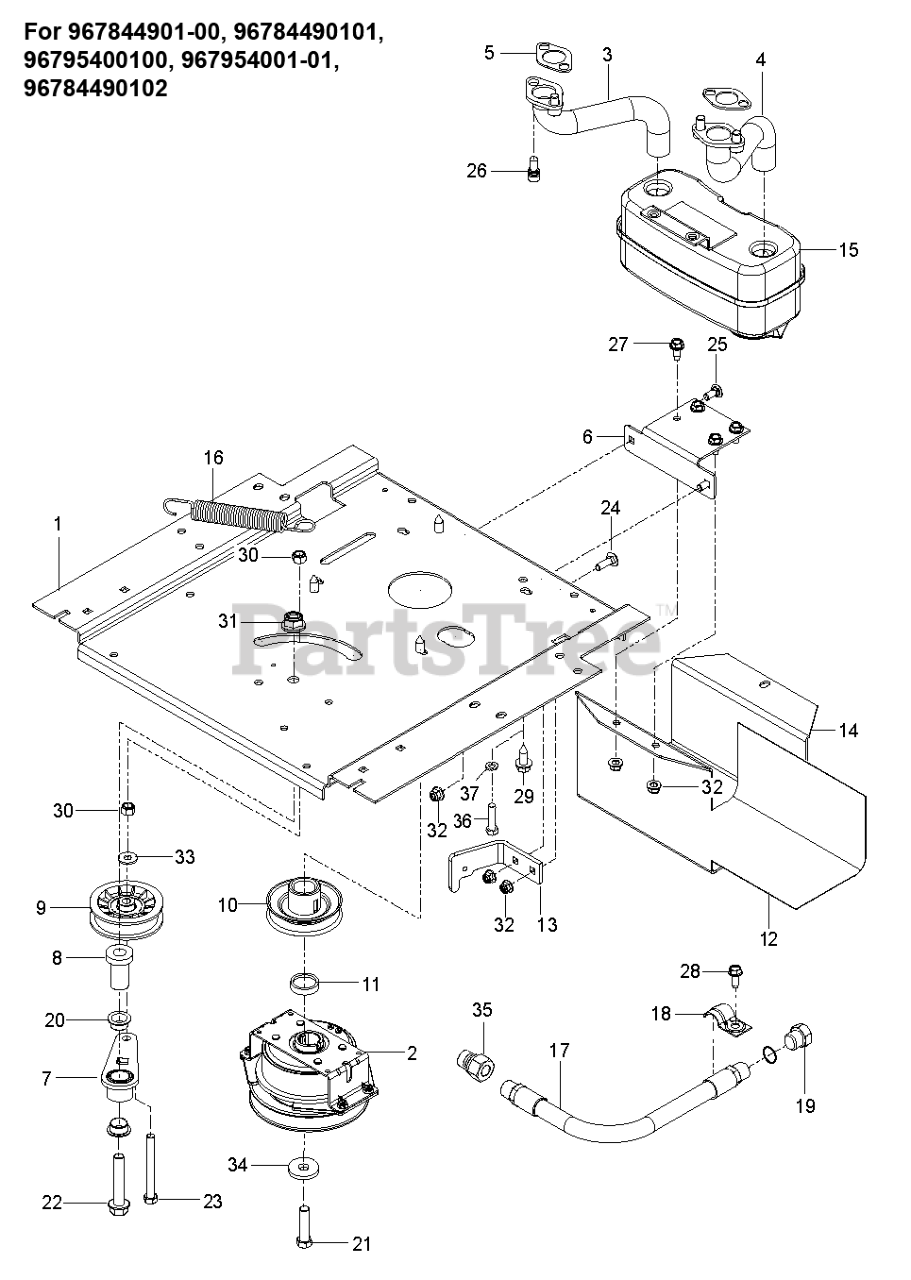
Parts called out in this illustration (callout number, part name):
1	PLATE ENGINE; RZ, 23IN BLACK
1	PLATE.ENGINE.PNT.23"FRAME.EDIP
2	CLUTCH.OGURA.5.0PD.GT1.5A-EH07
3	PIPE.EXHAUST.RH.CV18/20
3	TUBE.EXHAUST.RH.FR961/FR730
4	TUBE.EXHAUST.LH.FR961/FR730
4	PIPE.EXHAUST.LH.CV18/20
5	GASKET.EXHAUST.KOHL.CV18-CV26
6	BRACKET MUFFLER MS431BLK
7	ARM IDLER
8	SPINDLE.IDLER
9	PULLEY, IDLER RAKE & ZTR
10	PULLEY.ENGINE
11	SPACER.SPACER.625 W/OGURA.LCC
12	HEAT SHIELD
13	CLUTCH.STOP.OGURA LCC.BLACK
14	GUARD.MUFFLER.WO.TOW.HITCHX431
15	MUFFLER ASM TWIN
16	SPRING, DECK DRIVE
17	HOSE.ASSEMBLY.OIL.DRAIN
19	PLUG OIL DRAIN
19	BEARING.FLANGED.PLASTIC.3/4ID
20	BEARING.FLANGED.PLASTIC.3/4ID
21	CLUTCH BOLT7/16-20X2.5 GR524HR
22	BOLT.FLANGE.1/2-13 X 2.75.GRD5
23	HCS 3/8-16X3-1/2 TAPBLT GR5 ZD
24	RHSNB 5/16C X 1
25	BOLT 5/16C X 3/4" CARRIAGE
26	Screws
26	SCREW.SOCKET.HEAD.5/16-18
27	SCREW.THDROL.5/16-18X3/4.TTY
28	SCR 1/4-20X5/8 HEX SELF TAP ZD
29	SCREW 3/8-16X1
30	NUT 3/8-16 NYLOC
31	NUT, 1/2-13 HEX FLG NYLOC ZD
32	5/16-18 NYLOC FLANGE NUT
33	WASHER.5/16.FLAT.STE.STD.
35	ADAPTER, OIL DRAIN
36	BOLT
37	SLW 3/8 STD
